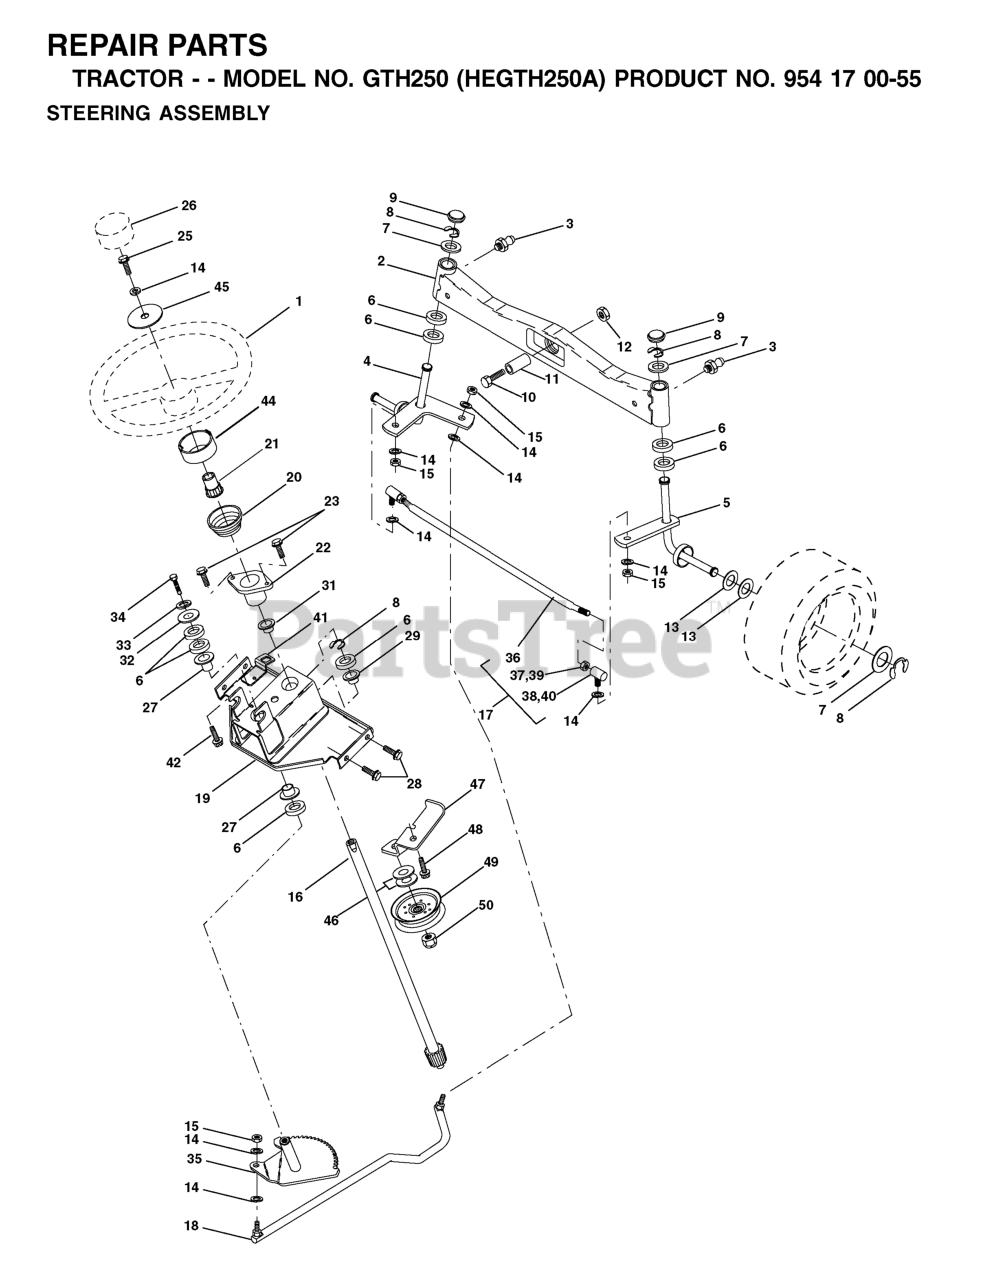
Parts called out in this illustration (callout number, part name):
1	STEERING WHEEL
2	AXLE.FRONT.CAST.MACHINE.W/ZERK
3	ZERK M
4	SPINDLE ASSY LH
5	SPINDLE ASM RH
6	THRUST WASHER
9	CAP.SPINDLE.BLACK
10	Bolt, Hex 5/8 -11 x 2 - 3/4 Gr. 5
11	TUBE, PIVOT AXLE
12	NUT-LOC,FLANGE LT
14	WASHER, LOCK 3/8
15	GRIPCO NUT
16	SHAFT ASM, STEERING
17	ROD ASSY/TIE BALL
18	DRAGLINK, BALL JOINT (3SPG1401
19	SUPPORT ASM., STEERING VGT
20	BOOT, STEERING
21	STEERING WHEEL ADAPTOR
22	BUSHING, STRG. BLK
23	SCREW.TT.#10-32X.5.3/8.FLANGE
26	CAP.WHEEL.STEERING.GREY
27	BRNG T
28	SCREW, 3/8-16X3/4
29	BEARING-FLANGE GT
31	BUSHING.NYLINER.
33	WASHER.LOCK.HVY.HLCL.SPR.5/16
34	BOLT.FIN.HEX.5/16-18X3/4
35	GEAR.ASM.SECTOR.
36	TIE ROD
38	JOINT
41	BRACKET INTERLOCK
42	Screw 5/16-18 x 1/2 Hex, Self Tapping 5/16-18 x 1/2
44	EXTENSION STEERING PREMIUM
45	Washer 13/32 x 1-1/20 x 11 Gauge
47	BRACKET ASM, IDLER STATIONARY
48	SCREW 3/8-16X3/4
49	PULLEY.IDLER.FLAT.46.PR.DR.
50	NUT LOCK FLG 3/8-16 UNC
